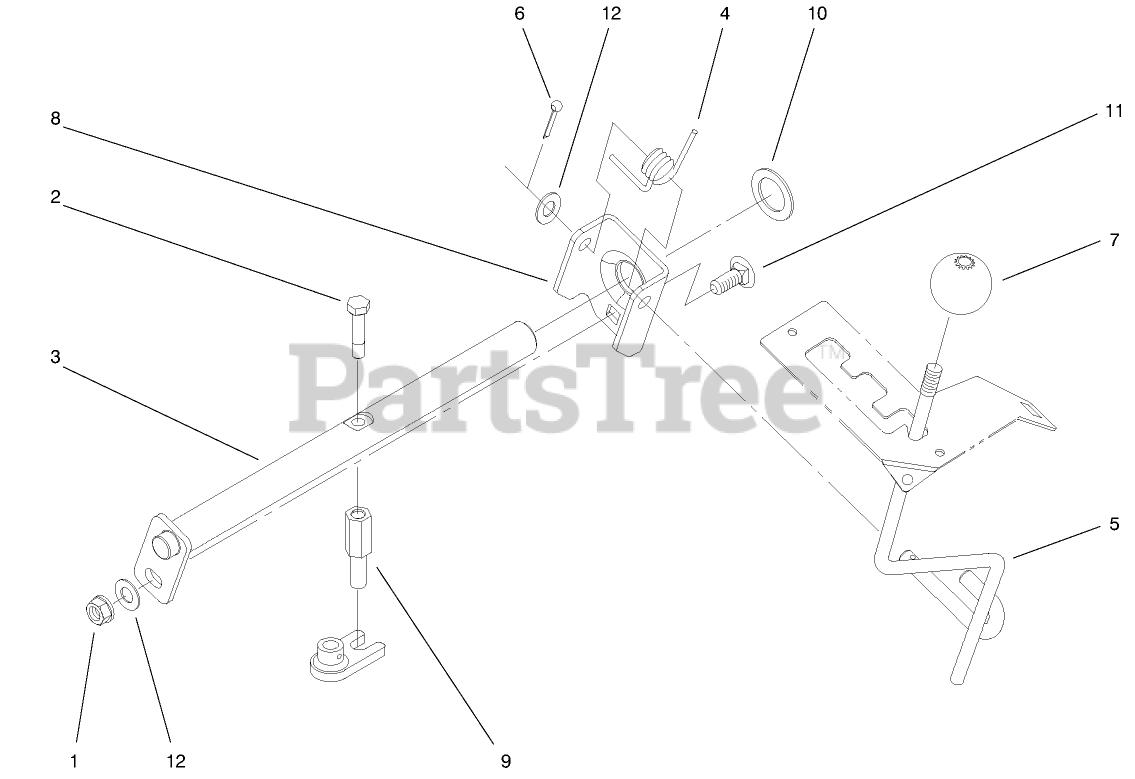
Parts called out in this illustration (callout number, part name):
1	NUT-LOCK, NI
2	SCREW-THREAD LOCKING
3	SHIFT ROD ASM
4	SPRING-TORSION
5	LEVER-SHIFT
6	PIN-COTTER
8	BRACKET-PIVOT
9	ROD-PIVOT, SHIFT
10	SPACER
11	SCREW-CARR
12	WASHER-FLAT
